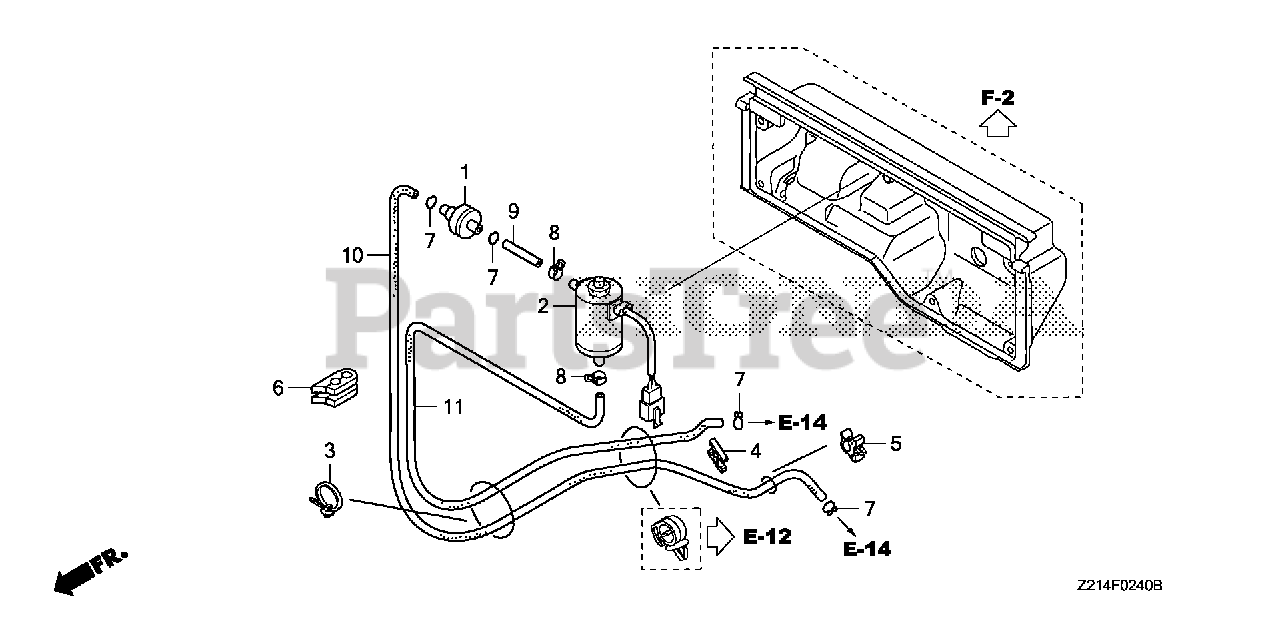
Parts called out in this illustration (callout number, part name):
1	VALVE, DASHPOT CHECK
2	VALVE ASSY., SOLENOID
3	BAND, HARNESS (98MM) (NATURAL)
4	CLIP, TUBE
6	GROMMET, TUBE
7	CLIP, TUBE (B7)
8	CLIP, TUBE (D8)
9	BULK HOSE, VACUUM (3.5X8000) (3.5X130)
10	BULK HOSE, VACUUM (3.5X8000) (3.5X130)
11	BULK HOSE, VACUUM (3.5X8000) (3.5X130)
